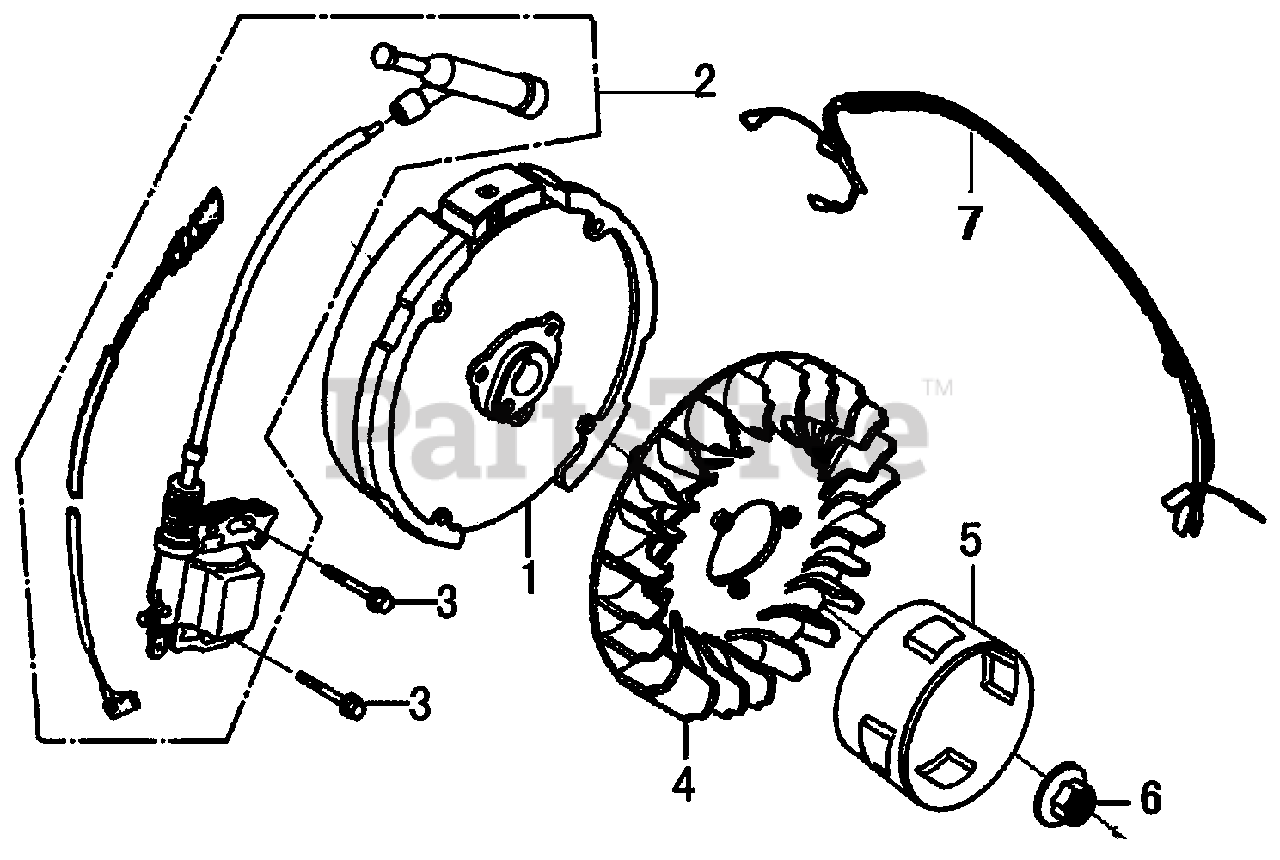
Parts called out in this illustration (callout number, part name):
2	COIL ASSY., IGNITION
3	BOLT, FLANGE, 6X25
4	FAN, COOLING
5	PULLEY, STARTER
6	NUT, SPECIAL
7	HARNESS, STOP SWITCH
